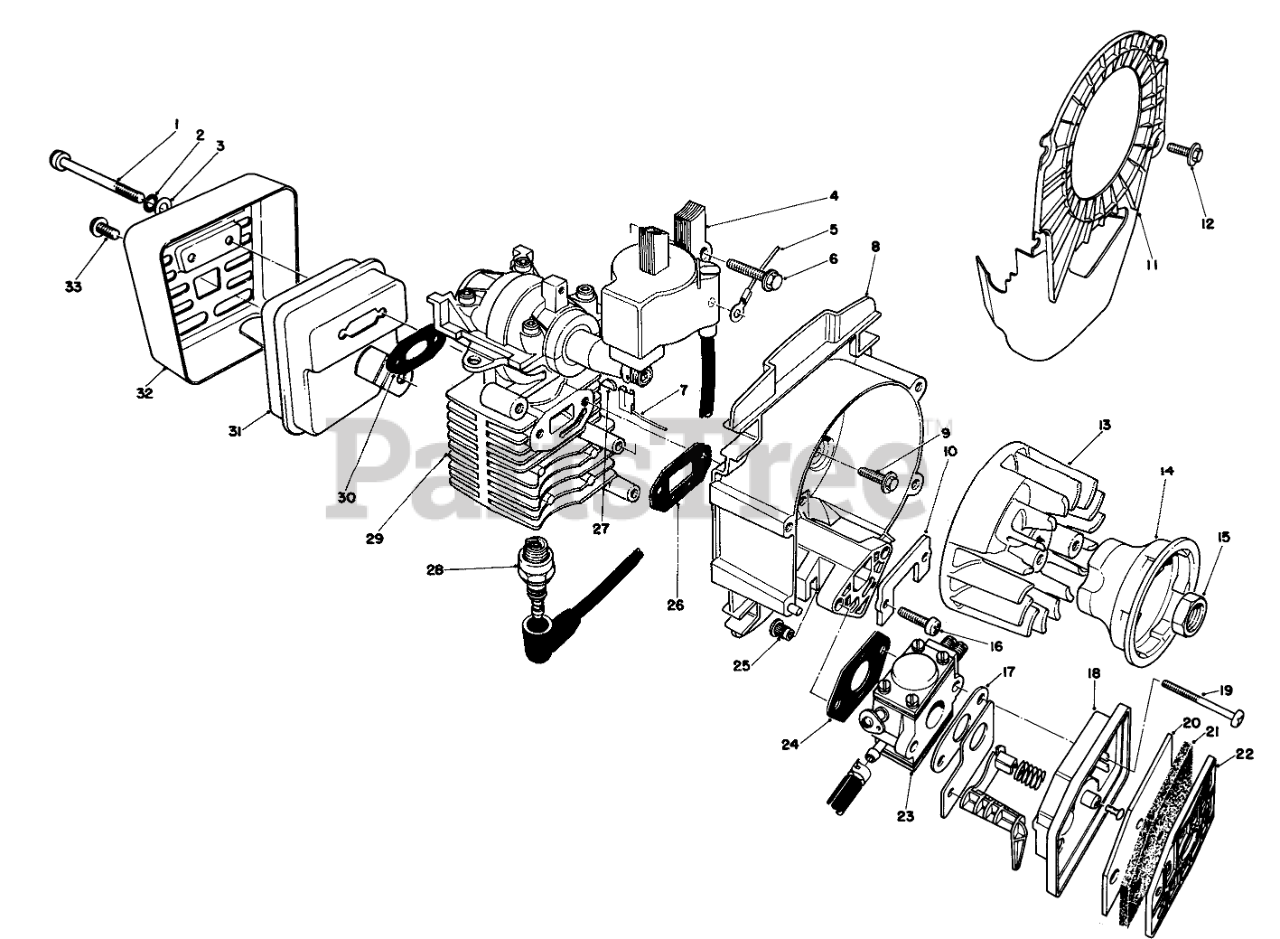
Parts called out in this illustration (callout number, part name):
1	MUFFLER SCREW
2	LOCKWASHER
3	Washer-Plain
4	BIM Module
5	Wire-Ground/Switch
6	Screw CDI
7	Wire-Coil/Switch
8	Backing Plate Assembly (Incl. Ref. #25)
9	Screw
10	Plate-Stress
11	Cooling Shroud
12	Screw-Shroud
13	Flywheel
14	Cup-Starter
15	NUT-JAM
16	Screw lntake
17	CHOKE GASKET
18	Choke & Spitback Cup Assy.
19	Screw-Carburetor
20	FILTER FELT
21	FILTER FOAM
22	FILTER COVER
23	CARBURETOR
24	CARB. GASKET
25	THREADED INSERT
26	INTAKE GASKET
27	FLYWHEEL KEY
28	SPARK PLUG (NGK)
29	SHORT BLOCK ASM
30	EXHAUST GASKET
31	Muffler Assembly
32	MUFFLER SHIELD WA
33	Screw, Muffler Tab
